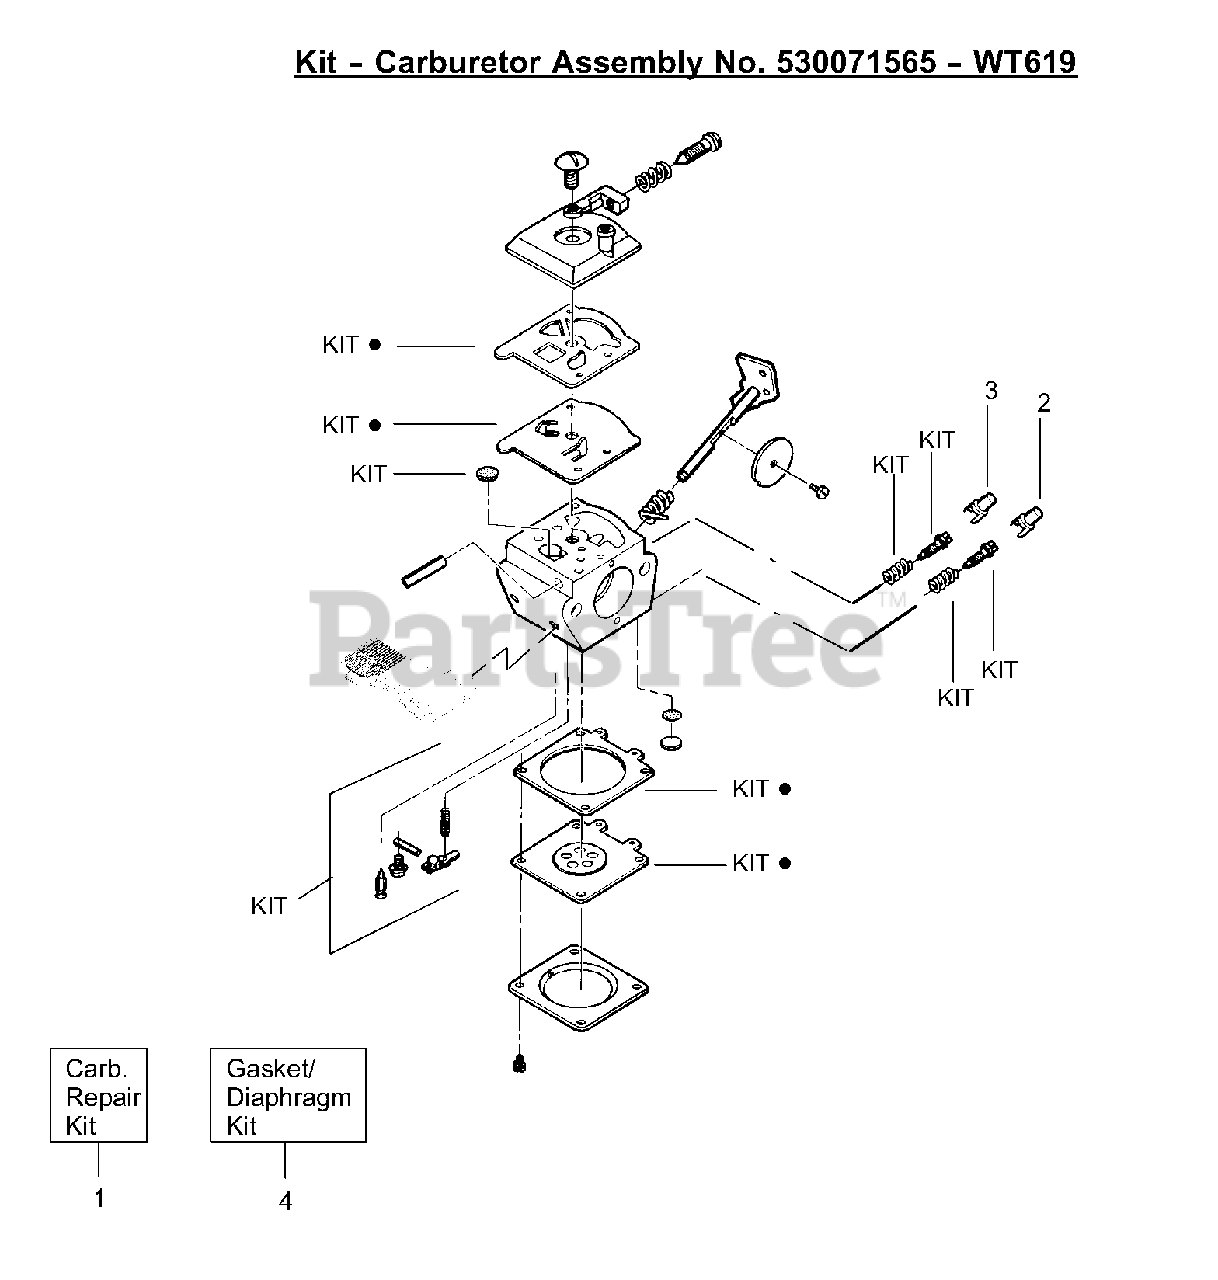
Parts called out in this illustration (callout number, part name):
1	Carburetor Repair Kit
2	Limiter Cap-Low (tan)
3	Limiter Cap-High (brown)
4	Gasket/Diaphragm Kit
530071565	Kit-Carburetor Assembly
